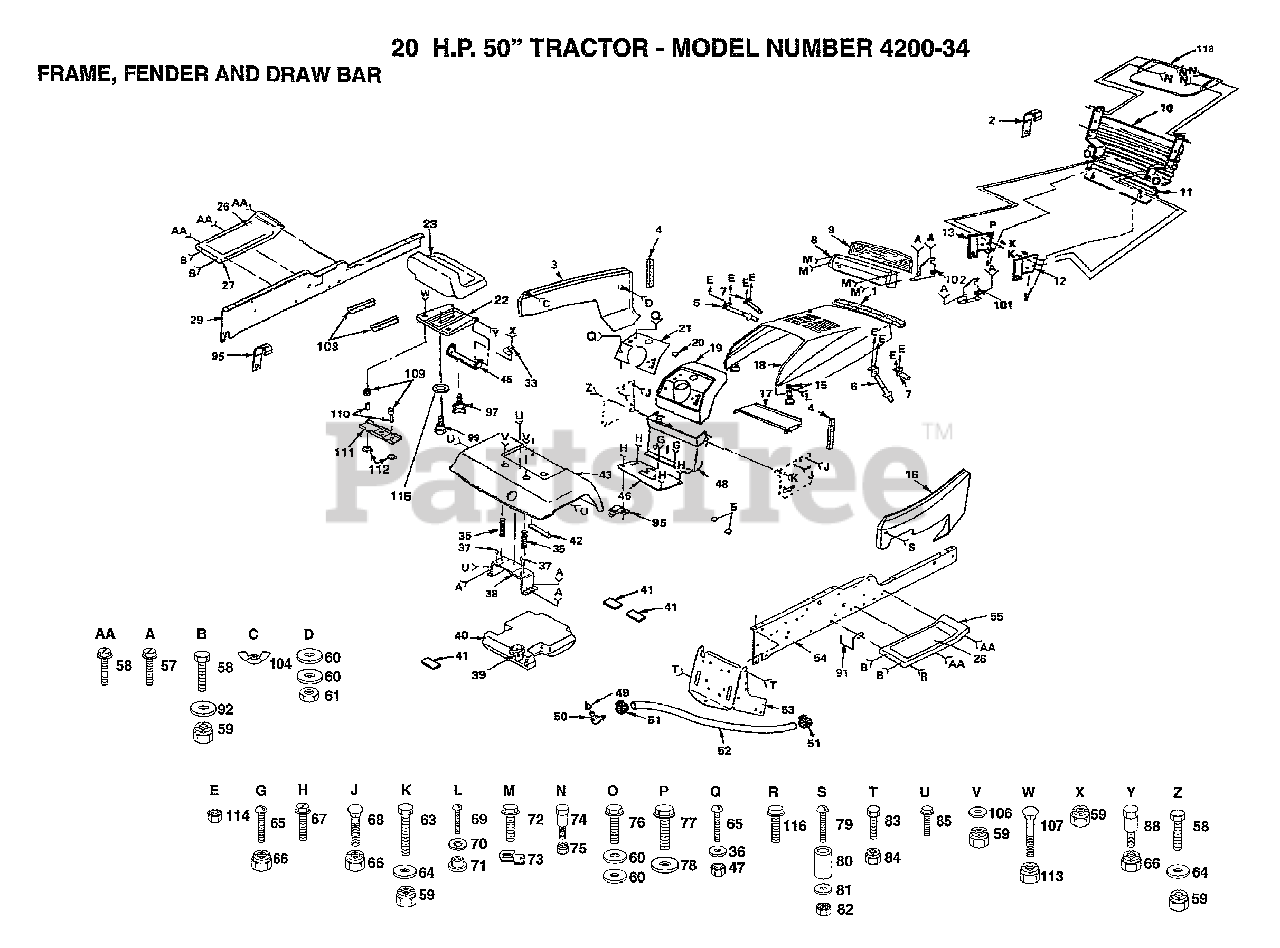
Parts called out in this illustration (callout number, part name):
1	FOAM STRIP T
3	SIDE PANEL LH
4	FOAM STRIP T
5	CAP SPRING
9	LENS LT
12	SUPPORT RH YTH
13	SUPPORT LH YTH
15	HOOD LATCH T
20	PLUG-DASH T
21	PLATE.SLKSCR.DASH
26	FOOTREST PAD
33	CLIP T
35	SPRING COMPRESSIO
36	WASHER
37	NUT-PUSH YT
41	PAD-SPACER LT
46	SADDLE.6SP.GT
48	DASH ASSEMBLY
49	BUSHING OUTLET T
50	STEM.TANK.FUEL
51	HOSE CLAMP
57	SCREW
60	WASHER PM
63	BOLT
64	WASHER
65	SCREW
67	SCREW
68	BOLT
69	SCREW
70	LOCKWASHER
71	WELDNUT
73	"""J"" FASTENER LT"
76	SCREW
77	SCREW
78	WASHER
79	SCREW
80	SPACER LT
81	WASHER
83	BOLT
84	NUT GTV
85	SCREW LT
91	BELT RETAINER GT
92	WASHER
97	"KNOB 1/2"" YT"
99	"BOLT,SHOULDER"
101	SUPPORT RH YTH
102	SUPPORT LH YTH
106	WASHER
108	STRIP FORM
109	SPRING COMPRESSED
110	SPACER SPLIT
111	BRKT SWITCH
112	BUSHING
114	NUT
115	WASHER
116	SCREW GTV
118	"SHIELD,HEAT"
